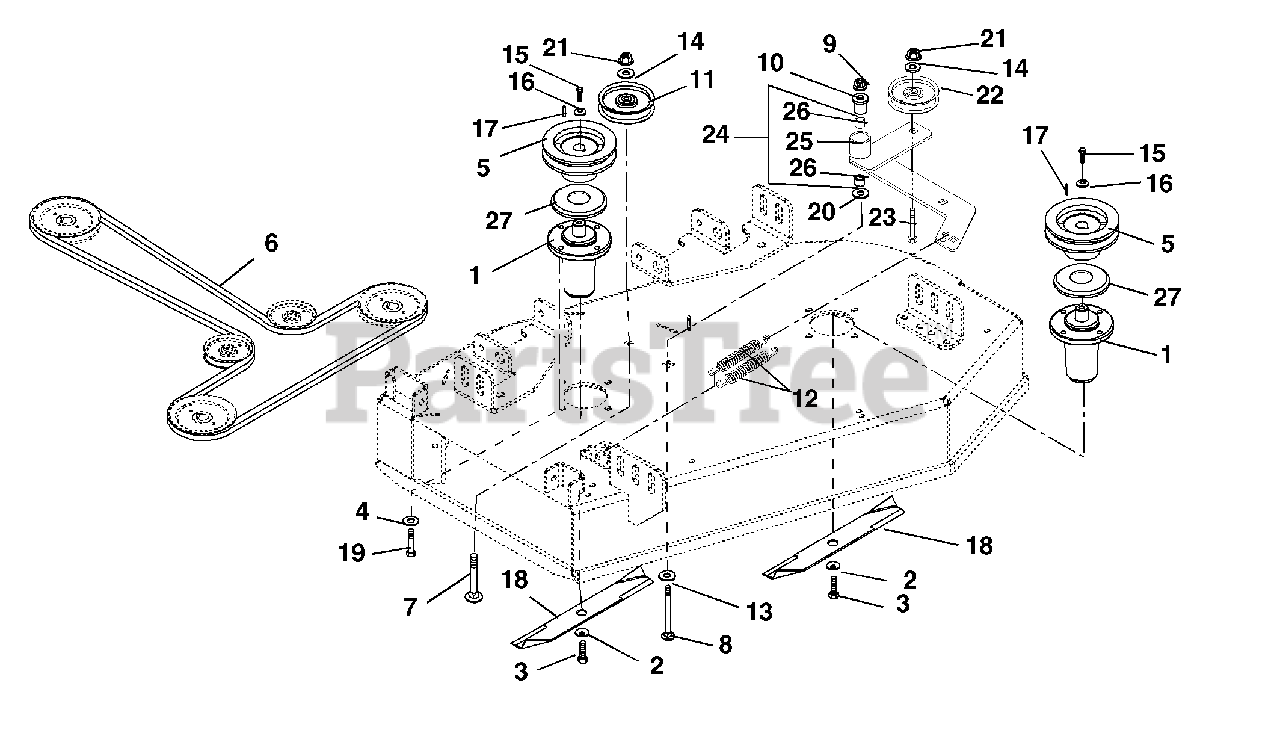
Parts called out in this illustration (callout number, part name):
1	Assembly, Maintenance Free Spindle
2	Washer-Bellville .63 x 1.625 x .14
3	Bolt-Hex .62-18 x 1.75 Grade 8
4	Washer-Locking .38 x .094 Regular
5	Sheave, 5.00 Spindle (1.00 I.D.)
6	V-Belt, B-Section 48.80 x .625
7	Bolt, Round Head Square Neck .38-16 x 2.75 Grade 5
8	Bolt-Round Head Square Neck .50-13 x 3.50 Grade 5
9	Nut-Locking-Top-Flange .50-13
10	Bearing, Pedestal Powdered Metal
11	Idler-Flat 4.00 x .38 (2.00 W)
12	Spring, Extension
13	Washer-Flat-Steel .755 x 1.375 x .062
14	Washer-Flat-Steel .375 x 1.125 x .065
15	Bolt-Hex .38-16 x 1.00 Grade 8
16	Washer-Cupped-Serrated .375
17	Key, Square .25 x .25 x 1.00
18	Blade, Mower Sand (314)
18	Blade, Mower Hi -Lift (056)
18	Blade, Mulching 50" Mower
19	Bolt-Hex .38-16 x 1.00 Grade 5
20	Washer-Flat-Steel .563 x 1.38 x .109
21	Nut-Locking-Top-Flange .38-16
22	Idler, Flat 4.00 x .38 (1.00 W)
23	Bolt, Round Head Square Neck .38-16 x 2.00 Grade 5
24	Assembly, Idler Pivot Arm (Contains Items 25 & 26)
25	Weldment, Idler Pivot Arm
26	Bearing, 1.00 x 1.12 x .75
27	Slinger-Dust
